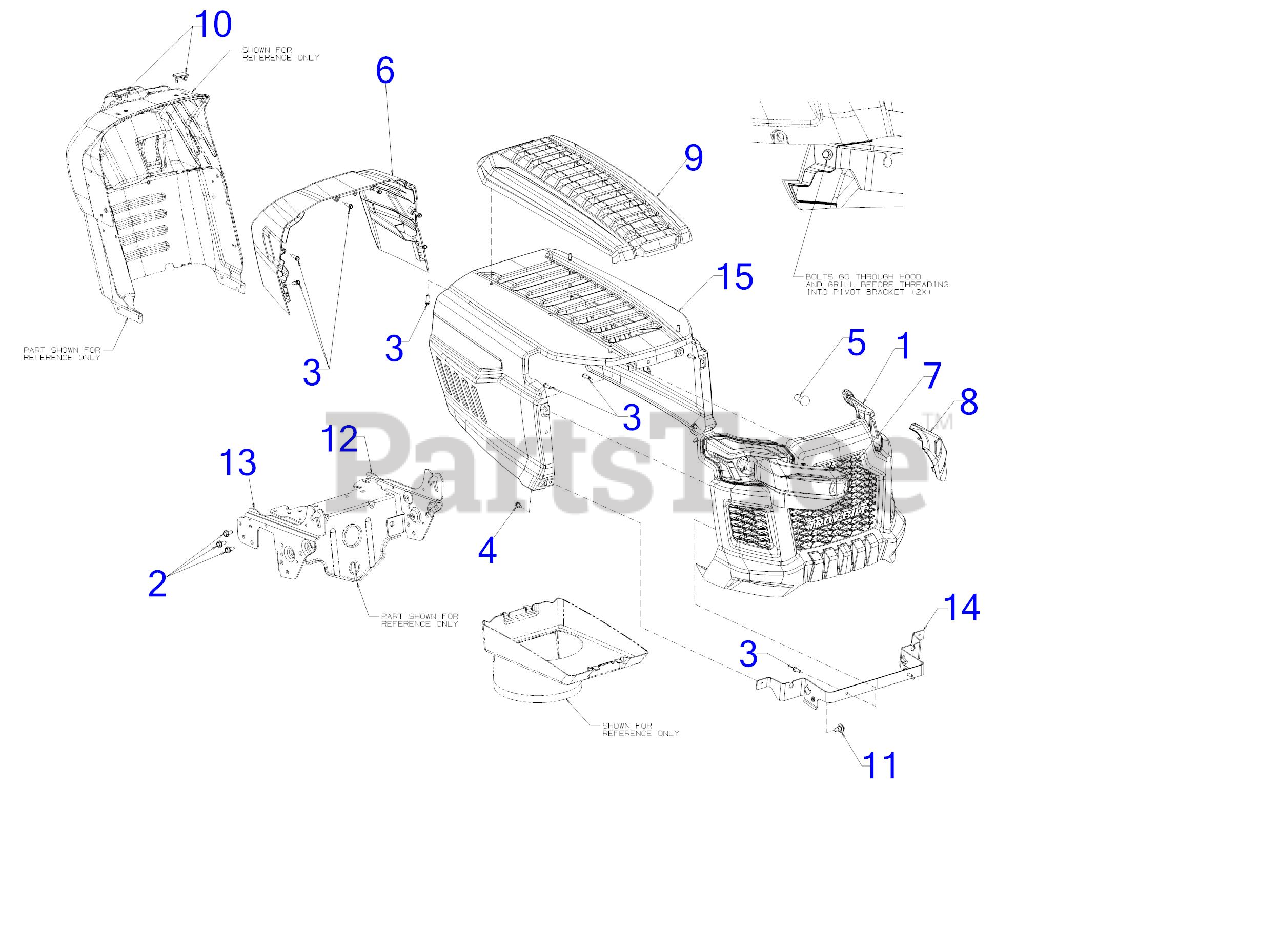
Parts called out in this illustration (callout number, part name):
1	FRONT GRILLE
2	SCREW 5/16-18 x .750
3	SCREW 1/4 x .750
4	SCREW 1/4-20X.625
5	MINIATUURE BULB 12V
6	HOOD COLLAR
7	HEADLIGHT LENS (RH)
8	HEADLIGHT LENS (LH)
9	HOOD SCOOP
10	HOOD BUMPER PAD
11	SHOULDER SCREW .43X.29X5/16-18 TT
